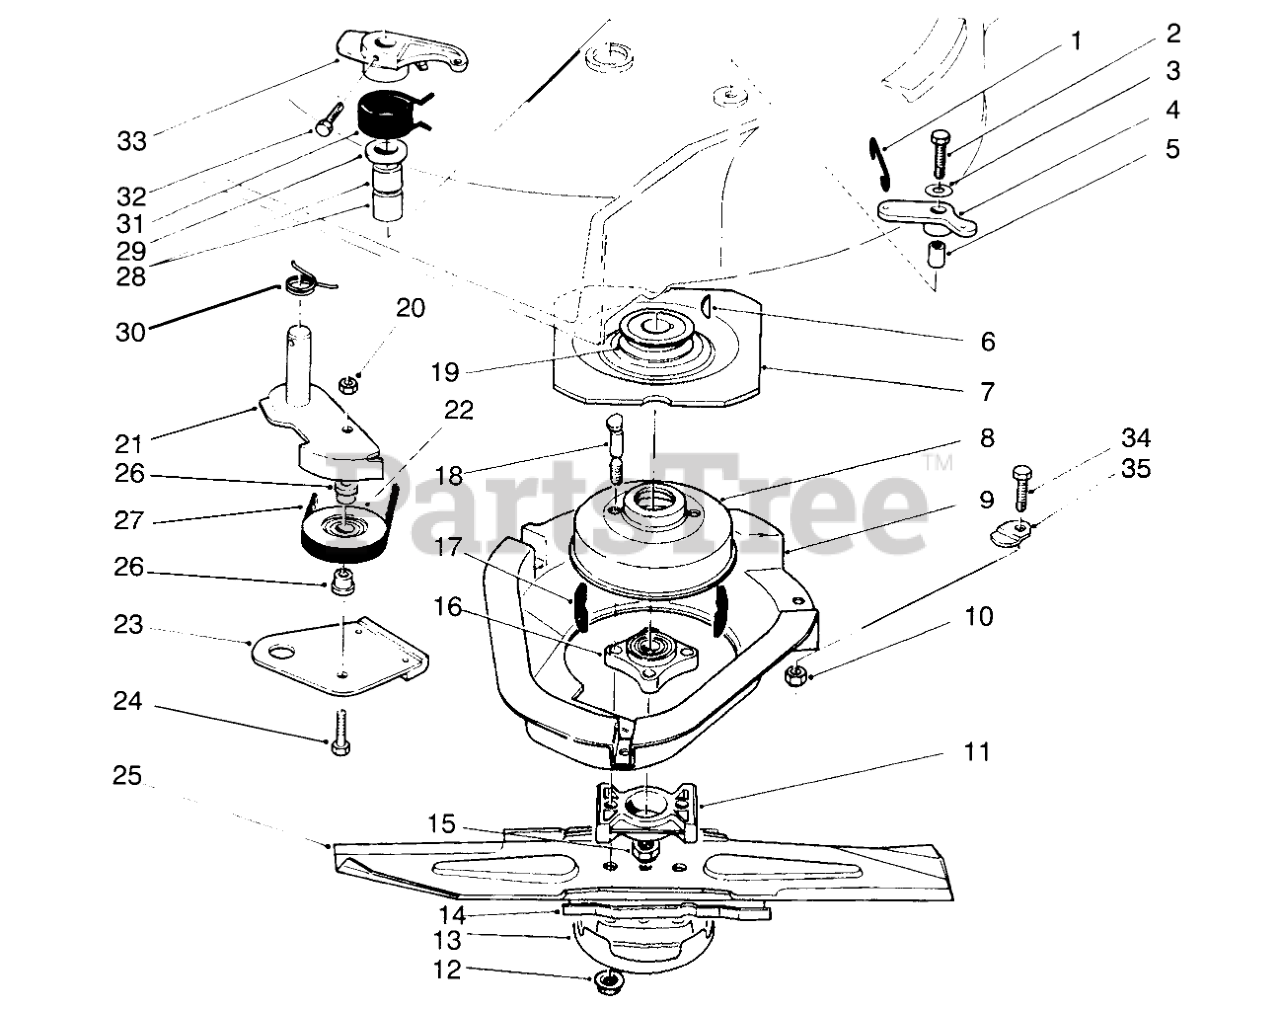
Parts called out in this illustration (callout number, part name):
1	LINK-CONTROL
2	SCREW-HH
3	WASHER-PLAIN
4	BELLCRANK
5	SLEEVE-BELLCRANK
6	KEY-WOODRUFF
7	Flywheel
8	Drum-Brake
9	Shield
10	NUT-LOCK, NI
11	SPACER-BLADE
12	NUT-LOCK
13	CUP-SCALP, ANTI
14	Accelerator
15	NUT-LOCK, NI
16	HUB ASM
17	DAMPENER-VIBRATION
18	BOLT-BLADE
19	PULLEY-DRIVER
20	NUT-LOCK, NI
21	ARM-IDLER
22	PULLEY-IDLER
23	BRAKE PLATE ASM
24	SCREW-HH
25	Blade
26	SPACER-PULLEY, IDLER
27	V-BELT
28	BEARING
29	WASHER
30	SPRING-TORSION
31	SPRING-TORSION
32	SCREW-HH
33	LEVER
34	SCREW-HH
35	SHIELD-RETAINER
